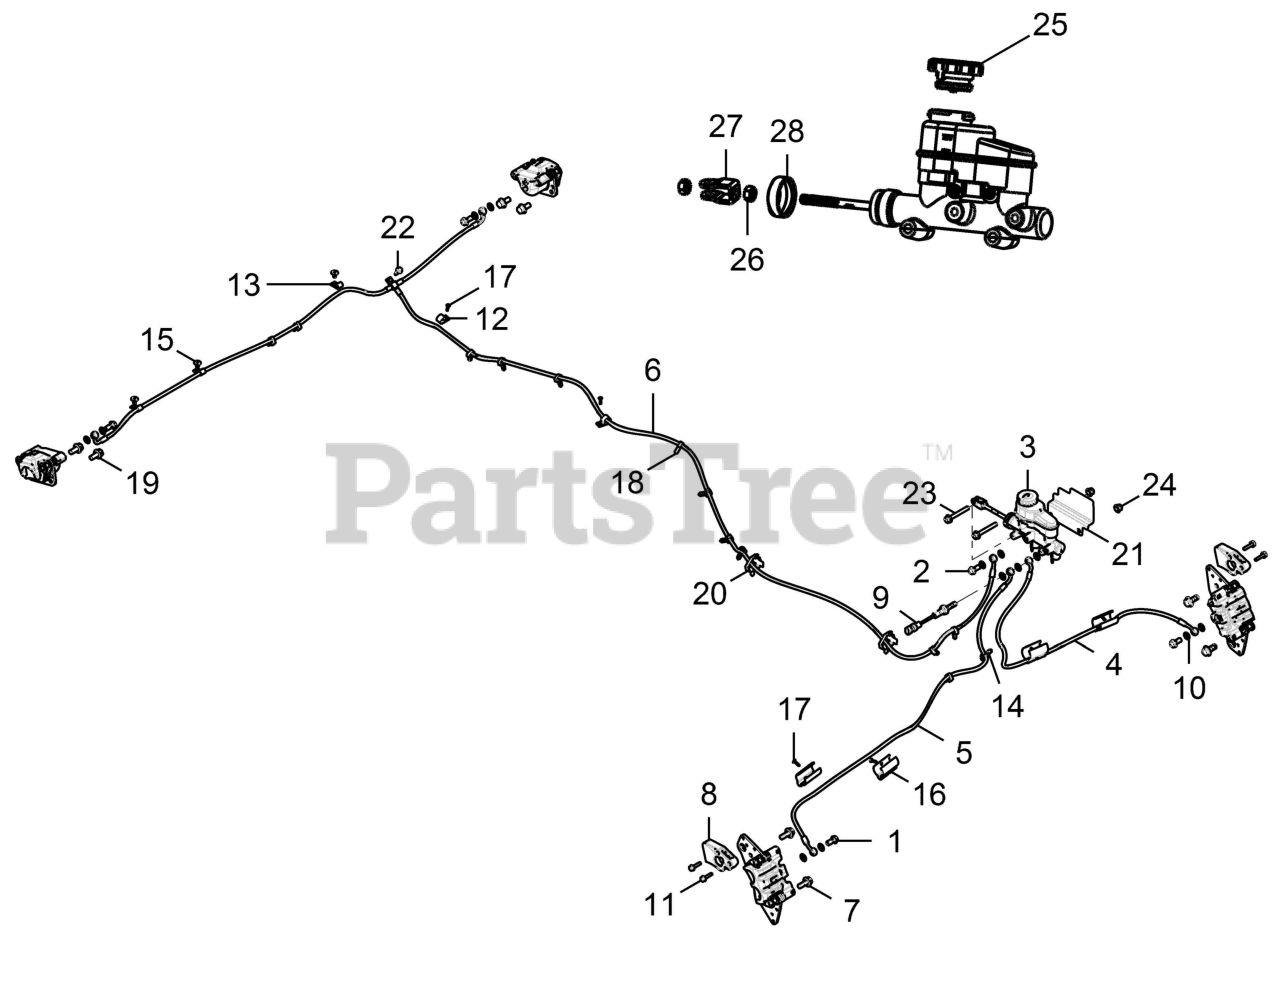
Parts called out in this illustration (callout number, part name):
1	BOLT-BANJO,10MMX1.00
2	BOLT-BANJO, 10MM X 1.25-6G
3	ASM-M/C-T,HBII,STD PUSH ROD
4	LINE-BRAKE,FRONT,LEFT,BRD
5	LINE-BRAKE,FRONT,RIGHT,BRD
6	LINE-BRK,3WAY,128",20B,0B,0B
7	BOLT-M10X1.25X25,HXFLG,W/PATCH
8	SCRAPER, FRONT BRAKE
10	SEAL-STAT-O-3/8,70EP
11	SCR-HXFL,M6X1.0X35 W/PATCHLOCK
12	CLAMP, CABLE
13	CLAMP,HOSE
14	CLIP-ROUTING
15	RIVET(50) *
16	RETAINER-BRAKE LINE,1"
17	POP RIVET(50)
19	BOLT-M10X1.25X20,HXFLG-OLV D
20	CLIP-ROUTING
21	SHIELD-MASTER CYL
22	SCR-M6X1.0X20,HXHD,FLG,TDFM,BL
23	SCR-HXFL-M8X1.25X60 8.8 ZOD
24	NUT-M8X1.25,FLG,NYLOC-OLIVE D
25	RESERVOIR CAP ASM.
26	NUT, HEX
28	DUST BOOT
